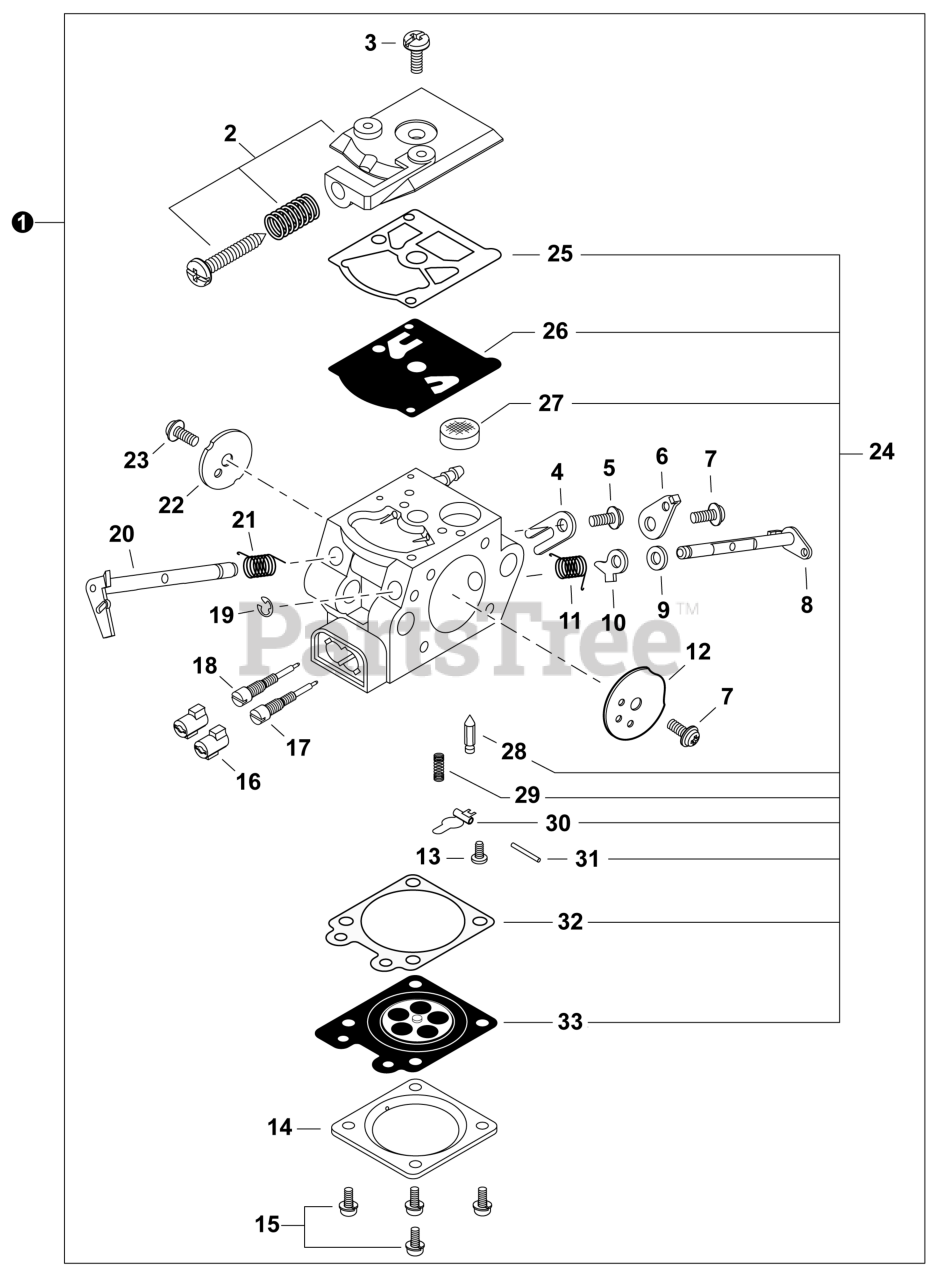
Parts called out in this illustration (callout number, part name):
1	CARBURETOR - GC-05-1
2	COVER ASSY, FUEL PUMP
3	SCREW
4	CLIP, SHAFT
5	SCREW
6	LEVER, THROTTLE
7	SCREW
8	SHAFT, CHOKE
9	WASHER
10	LEVER, FAST IDLE
11	SPRING
12	VALVE, CHOKE
13	SCREW
14	COVER, METERING DIAPHRAGM
15	SCREW
16	CAP, LIMITER
17	NEEDLE, HIGH SPEED
18	NEEDLE, LOW SPEED
19	E-RING
20	SHAFT, THROTTLE
21	SPRING, THROTTLE RETURN
22	VALVE, THROTTLE
23	SCREW
24	REPAIR KIT, CARBURETOR
25	GASKET, FUEL PUMP
26	DIAPHRAGM, PUMP
27	SCREEN, FUEL INLET
28	VALVE, INLET NEEDLE
29	SPRING, METERING LEVER
30	LEVER, METERING
31	PIN, METERING LEVER
32	GASKET, METERING DIAPHRAGM
33	DIAPHRAGM, METERING
